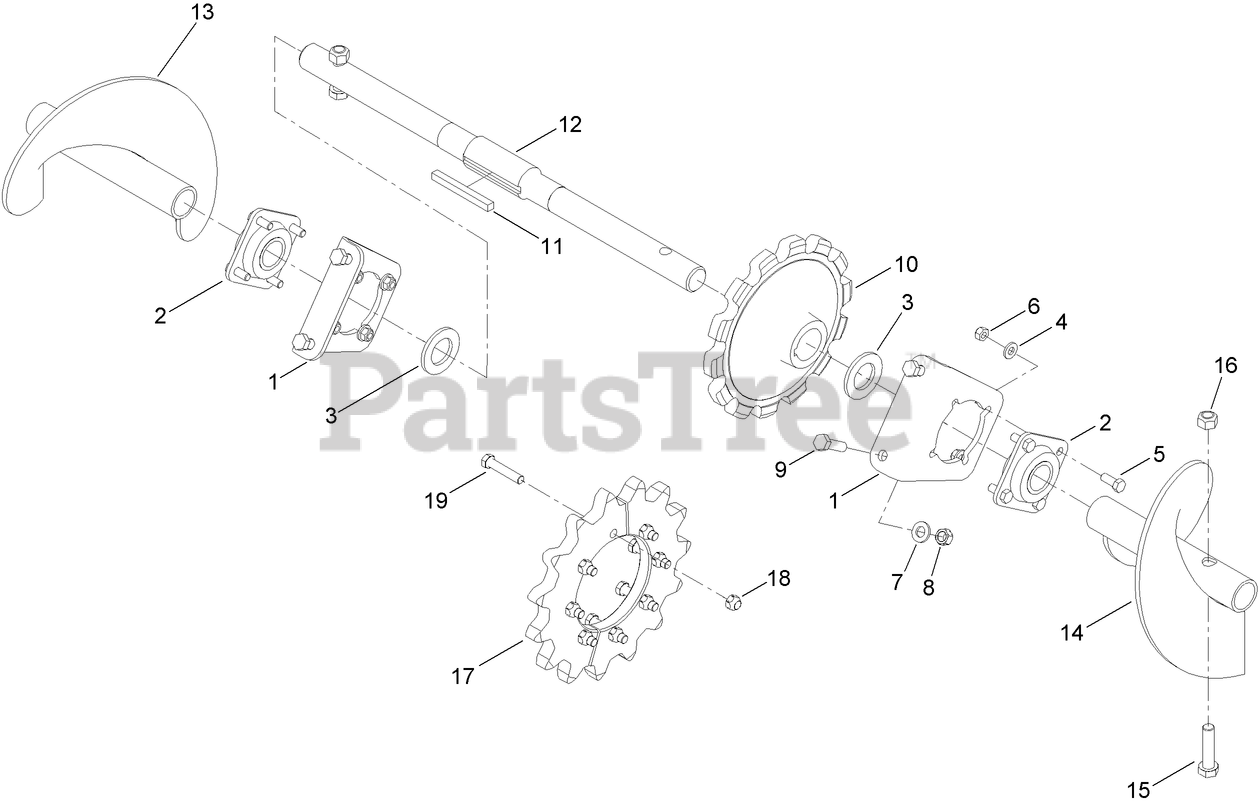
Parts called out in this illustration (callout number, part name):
1	ANGLE-MOUNT, AUGER
2	BEARING
5	SCREW-HH
6	LOCKNUT
7	WASHER-FLAT
8	NUT-CROWNLOCK
9	SCREW-HH
10	SPROCKET-AUGER, 14T
11	KEY-SQUARE
12	SHAFT-auger
15	SCREW-HH
16	NUT-LOCK
17	SPROCKET-DRIVE, TRENCHER
18	NUT-HEX
19	SCREW-HH
